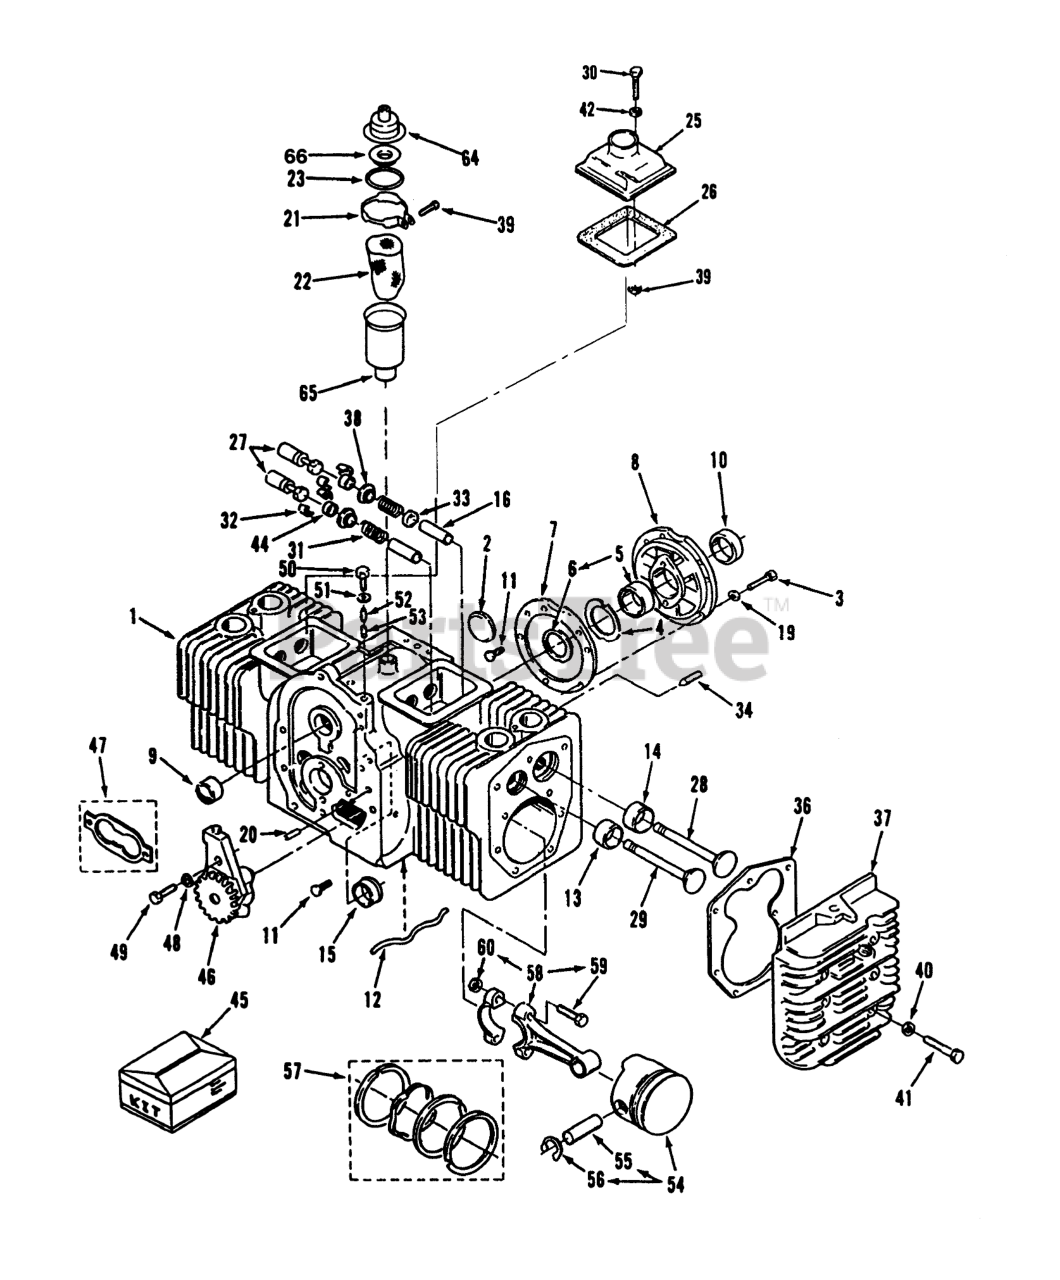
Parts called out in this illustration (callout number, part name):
1	CYLINDER BLOCK
3	HEX HD CAPSCREW
5	BEARING KIT (STANDARD SLEEVE)
6	WASHER
7	Gasket
8	PLATE-BEARING, REAR
9	WASHER
10	SLEEVE-BEARING
11	Screw
12	OIL TUBE
13	Standard
14	Standard
15	Standard
16	Guide-ExhaustValve
19	Washer
20	Pin
21	Clamp
22	FILTER
23	SEAL - O-RING
25	VALVE-COVER L.H.
26	GASKET
27	Tappet
28	Intake Valve
29	Intake Valve
30	HHCS 1/4-20 X 1 3/4
31	Spring
32	VALVE SPRING LOCK
33	Seal
34	Screw
36	Gasket
37	Right Side
38	Washer
39	SCREW-TAPPING, ROUND HEAD
40	WASHER
41	Bolt
42	Washer
44	VALVE CAP
45	ENGINE GASKET KIT
46	Oil Pump
47	Oil Pump Gasket Kit
48	WASHER-FLAT
50	SCREW-HH
51	Washer
52	Spring
53	Piunger
54	Standard
55	Pin-Piston
56	Retaining Ring
57	RING/PISTON KIT
58	CONNECTING ROD W/NUT
59	Rod Bolt
60	Nut
64	BREATHER-CAP AND VALVE
65	TUBE-BREATHER
66	SCREEN-BREATHER TUBE
